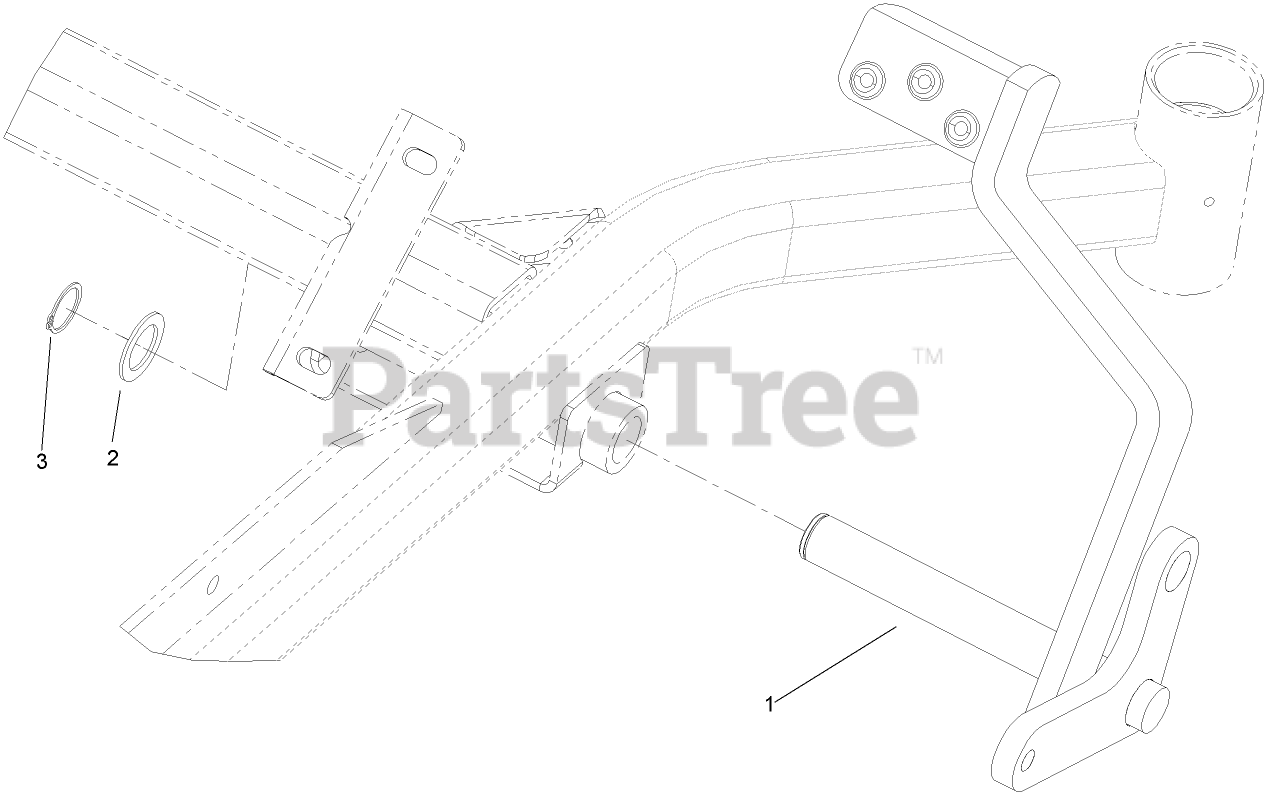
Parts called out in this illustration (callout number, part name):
1	LIFT-DECK, RH FRONT
2	WASHER-SPACER
3	RING-RETAINING
